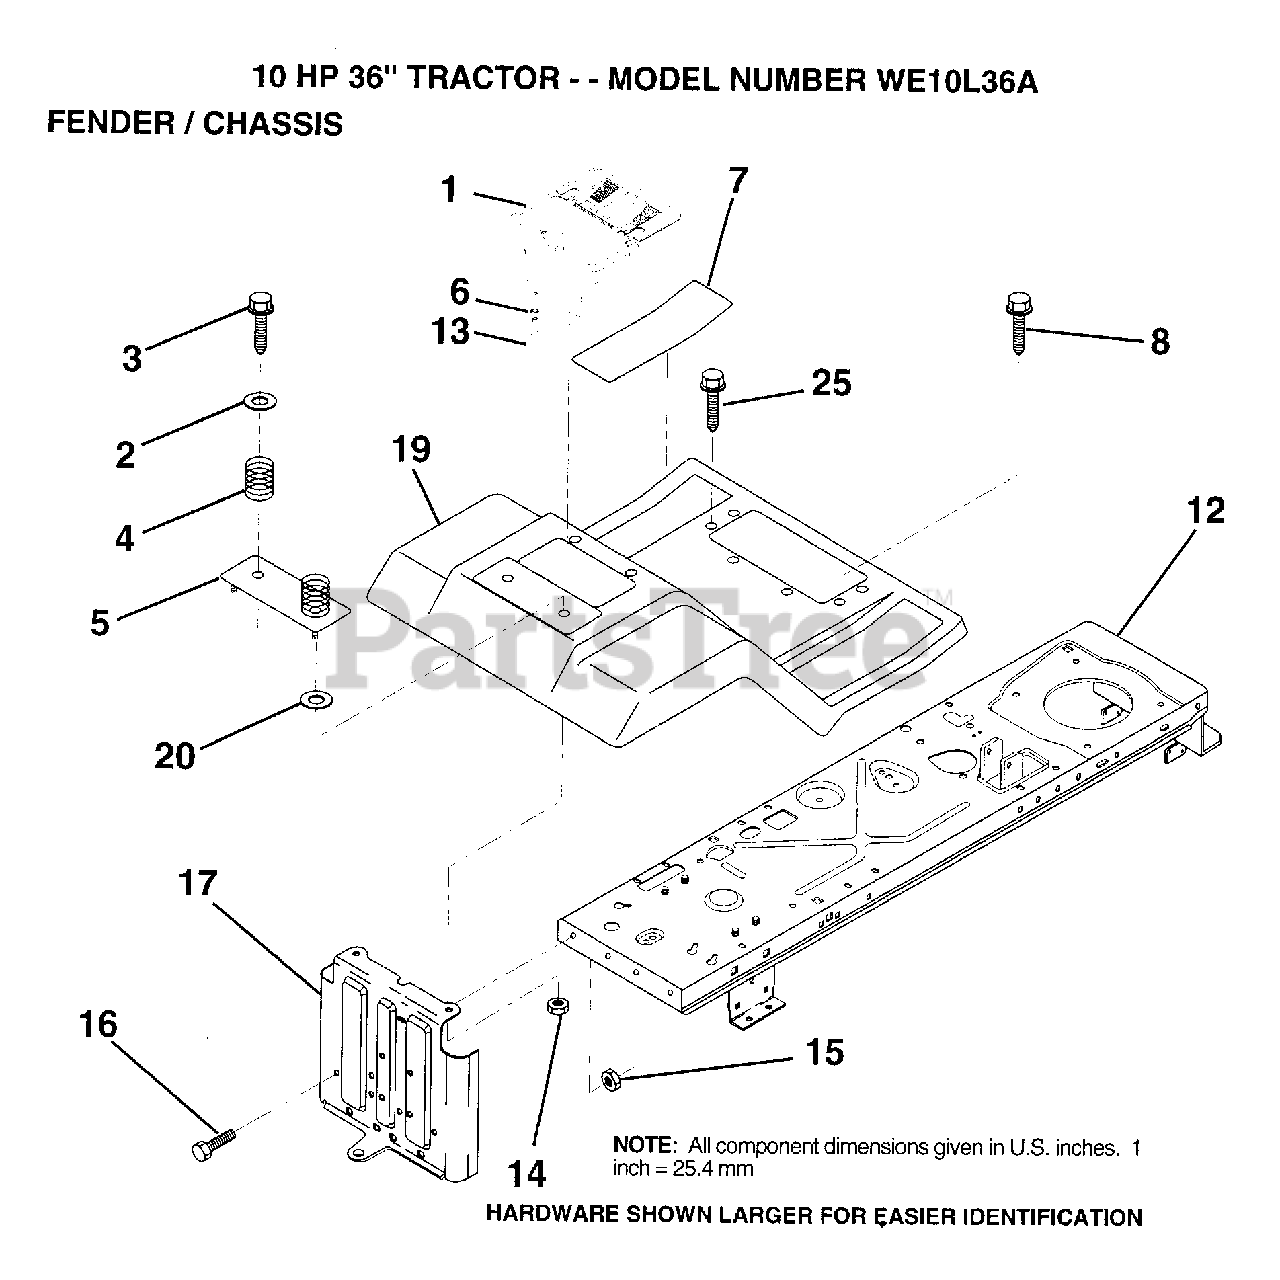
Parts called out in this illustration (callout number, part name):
2	WASHER
3	SCREW
4	SPRING COMPRESSIO
5	"PLATE, BATTERY"
6	HOSE CLAMP T
7	PAD FOOTREST
8	SCREW
13	TUBE T
14	NUT
16	BOLT
17	DRAWBAR
25	SCREW TI
